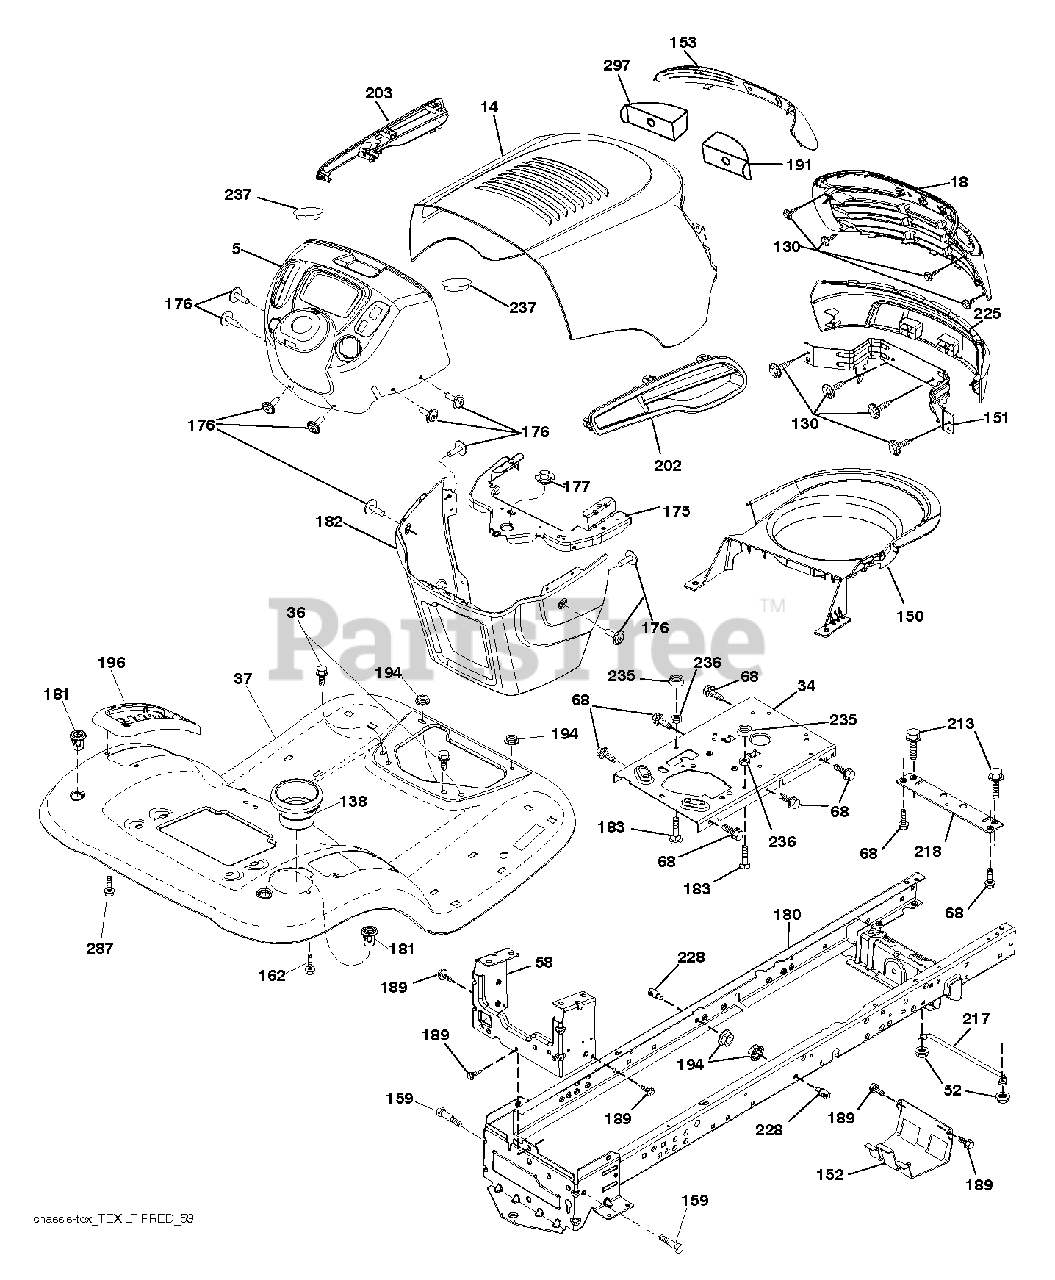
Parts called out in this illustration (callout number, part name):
34	PLATE.ENGINE.WELDED.CHASSIS
36	SCREW 5/16"
52	LOCKNUT
58	DRAWBAR UPPER 2PC SMALL FENDER
130	SCREW.#10 X 0.750.BOS THREAD
138	CUPHOLDER.TL.TEX.BLACK
151	BRACKET.PIVOT.ALPHA.LT
152	SHIELD BROWNING
153	LENS.PREDATOR.LT
159	SCREW, 3/8-16X3/4
162	SCREW.HI-LO.CONSOLE
175	CROSSMEMBER
176	SCREW.#10-24X5/8.RN.QU
177	BUSHING STEERING
181	FEND/FTRST.PCH.CPH.NFW
182	DASH.LWER.PREDATOR/HUSQ.LT
183	BOLT.5/16-18X1-1/4 FULL THD
189	SCREW
191	INSERT.REFLECT.PREDATOR.LT.RH
194	NUT LOCK HEX FLANGE 5/16-18
196	CONSOLE.ASM.DECKLFT.BL/RBT.TLT
213	BOLT
217	ROD.PIVOT.HOOD
218	X-PIECE.HOOD.STOP.NON/
228	STUD.FASTNER.W/ANTI-ROTATE
235	SPACER FENDER
236	NUT.CENTERLOCK.5/16-
297	REFLECTOR.INSERT.PRED.LH.LT
